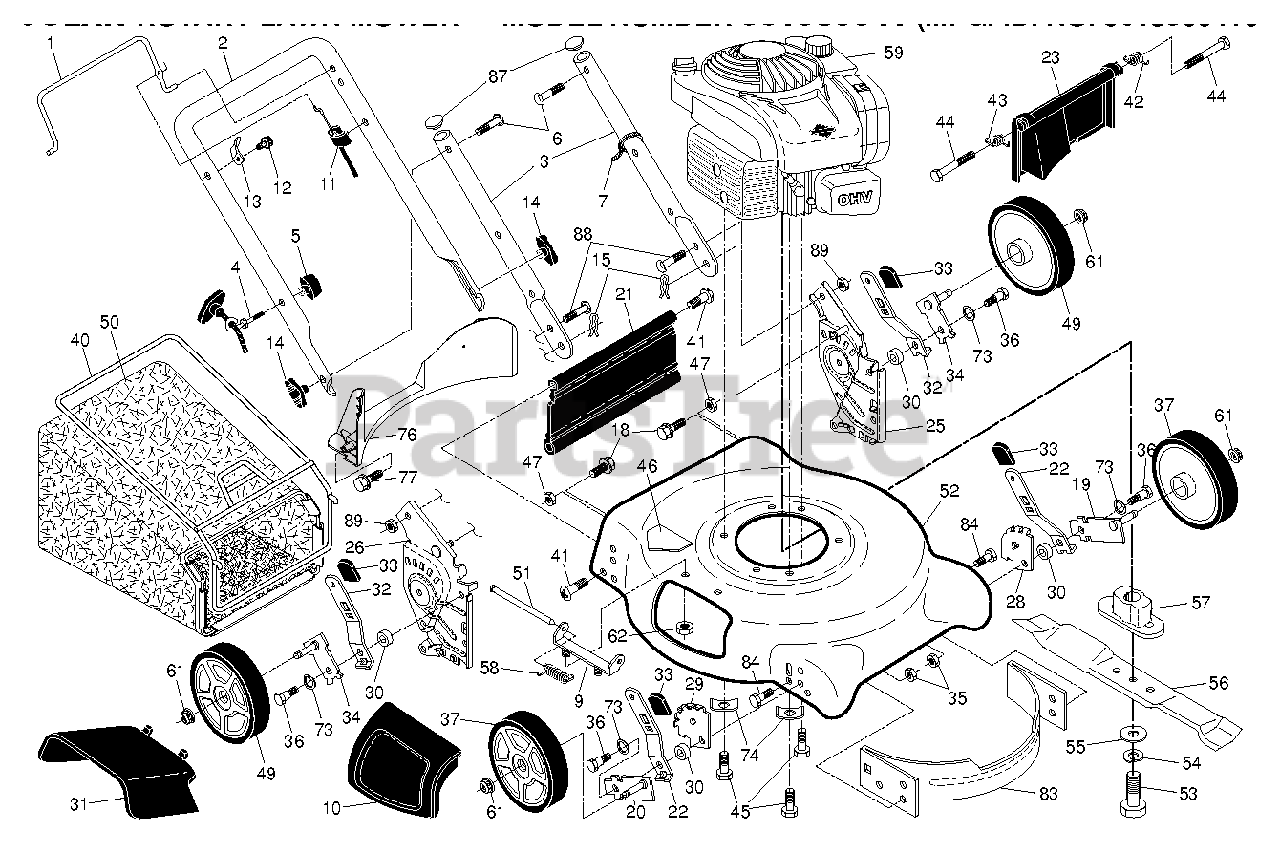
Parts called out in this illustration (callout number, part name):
1	BAIL.CONT.D.STRAIGHT.PUSH.BLK
2	HANDLE.UPPER.ECONOMY.BLACK
3	HANDLE.LOWER.DOME.BT.BLACK
4	Rope Guide, Blk Zinc Chrom
5	T-KNOB.NEW ROPE GUIDE
6	BOLT, HANDLE 5/16-18X1.75
7	TIE GUIDE
9	BRACKET.ASM.HOUSING.EZ.MUL
10	MULCH DOOR
11	CABLE.MZR.RATO.22"LOW.
13	BRACKET.UPSTOP.RT
15	HAIRPIN COTTER
18	SCREW 1/4X20
19	AXLE ARM ASSY FRONT LH
20	AXLE ARM ASSY FRONT RH
21	KIT.SKIRT.21 DOMED.W/LIP
22	SELECTOR SPRING, FRONT
23	REAR DOOR ASSY
25	BRACKET.ASM.HAND.LW.21.LT.BLAC
26	BRACKET.ASM.HAND.LW.21.RT.BLAC
28	BRACKET.ADJ.5.LTAB.LG.HOLE.ABS
29	BRACKET.ADJ.5.RTAB.LG.HOLE.ABS
30	SPACER.HEIGHT.ADJUSTER
31	CLIP ON DISCHARGE GUARD
32	SPRING.SELECTOR.21RD.HTTRT.BZP
34	ARM.ASM.AXLE.REAR.5/9.POS.BZP
35	NUT.FLANGE.HEX.5/16X18.BLACK
36	SHOULDER BOLT 5/16-18
40	FRAME.BAG.21.REAR.DOMED.PUSH
41	SCREW.1/4-20X21/4.HEX.
42	SPRING.LH.22.REAR.DOOR.EZ.EMPT
43	SPRING.RH.22.REAR.DOOR.EZ.
45	BOLT 3/8-16X1-1/8
46	No Step Decal
47	NUT.71038.31-18.HEX.NYLOCK
49	FENDER.550.LT.W/SFT.W/O.CUP
50	GBAG.24710513S.POULAN.BLK
51	ROD.HINGE.COMBI-C
52	HOUSING.21".MC.PUSH.YELLOW.E/F
53	SCREW, HEX HD 3/8-24 X 1-3/8
55	WASHER,HARDEN
56	BLADE.21.PUSH/RWGD/FWGD
57	ADAPTOR.BLADE.7/8
58	TORSION SPRING
61	NUT.HEX.FLANGE.3/8-16.LOCKNUT
62	LOCKNUT.NYLOC.1/4-20
73	WASHER.CURVED.CYLINDRICAL
74	WASHER.ENGINE.BZP
76	BAFFLE.REAR.PLASTIC.21.RD.ECON
77	SCREW.HX.13X.750
83	BAFFLE.FRONT.21.DOME.US
84	BOLT.5/16HEX.WHS.HD
87	PLUG.PLASTIC.7/8".14-20.GAUGE
89	LOCKNUT-FLANGE 5/16-18
